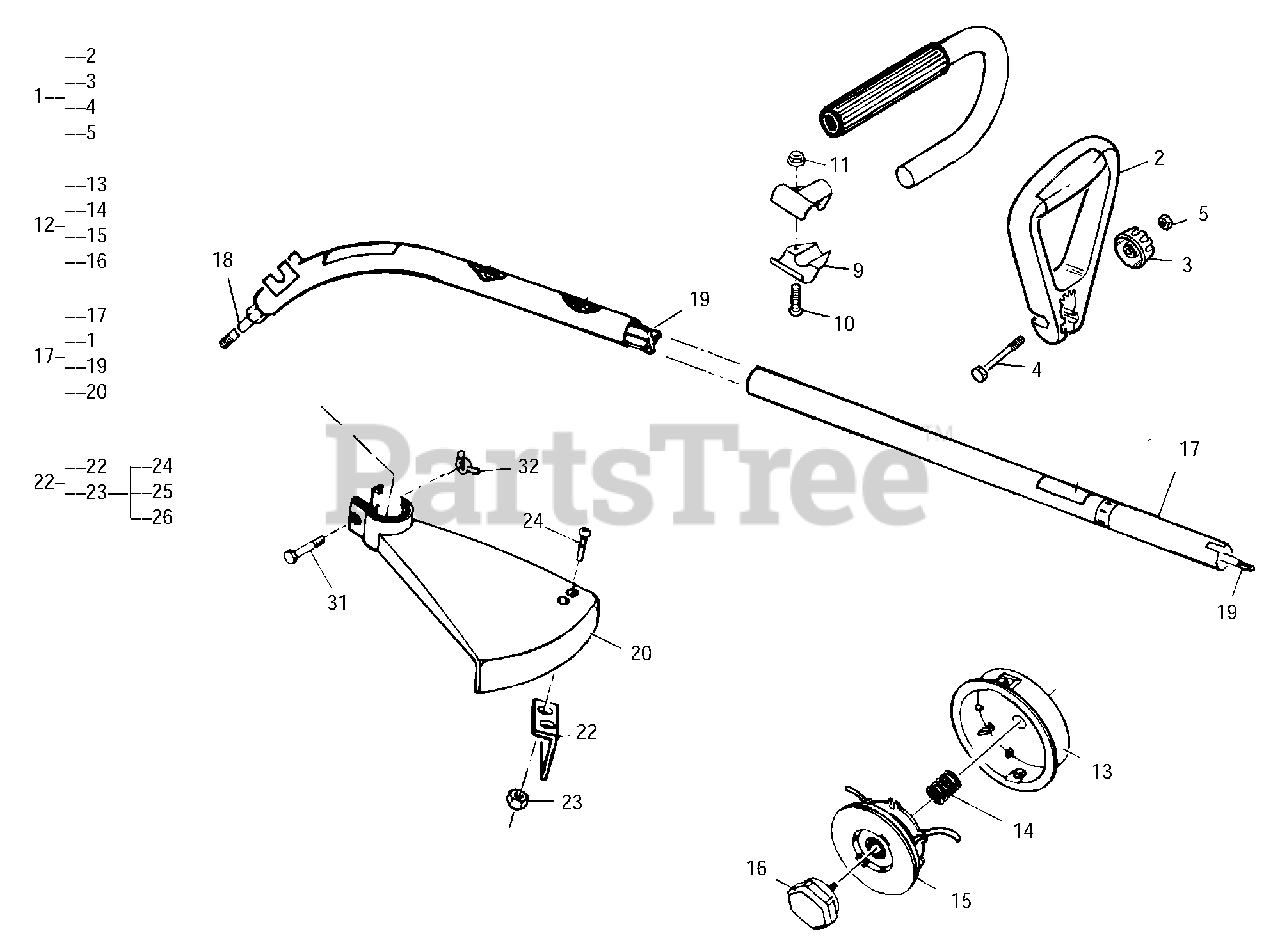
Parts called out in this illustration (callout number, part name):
1	Handle, Delta Kit
2	Assist Handle w/Cap Asy
3	Knob
4	Bolt, 1/4 in.-20 x 2.5 Hx Cap
5	Nut, 1/4 in.-20 x .226T
9	Clamp, Handle
10	Screw
11	Nut, 10-24
12	Kit, Stringhead, Small
13	Housing/Eyelet Asy w/Collar
14	Spring, Mc C Stringhead
15	Kit, Line on Spool, M-Sm
16	Kit, Knob Asy, Small
17	Housing Asy, Outer, 44"
17	Housing Asy, Outer, 48"
18	Clip, Spring External
19	Shaft, Flex, Plus Clip, 44"
19	Shaft, Flex, Plus Clip, 48"
20	Shield Asy, Grass, R, 17in.
21	Kit, Knife
22	Cutter
23	Nut, Lock 10-24 Hex
24	Screw, 10-24 x .50 Torx
31	Screw, M6 x 1.0 Hex
32	Nut, Wing M6 x 1.0
